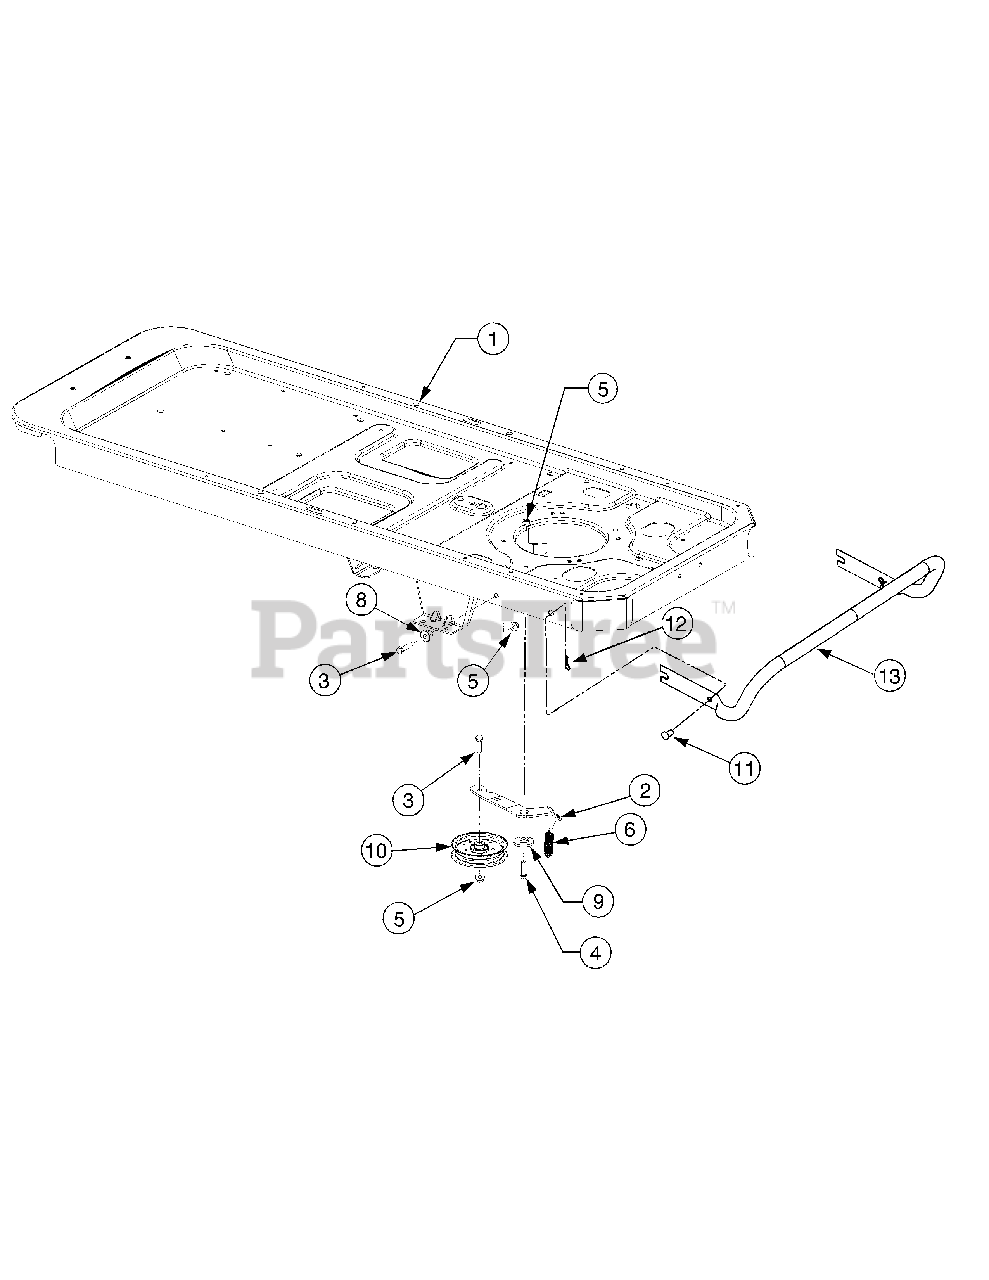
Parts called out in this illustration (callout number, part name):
3	Hex Screw 3/8-16 x 1.50
4	Hex Bolt 3/8-16 x 1.25
5	Flange Lock-Nut 3/8-16 Gr. F Nylon
6	Ext. Spring 5.06" Lg.
8	Shoulder Spacer .38 x 1.0 x .70
9	Shoulder Spacer .884 x .190
10	Idler Pulley w/Flange 4.25 Dia
11	Clevis Pin .50 x .78" Lg.
12	Cotter Pin .080 x 1.56
